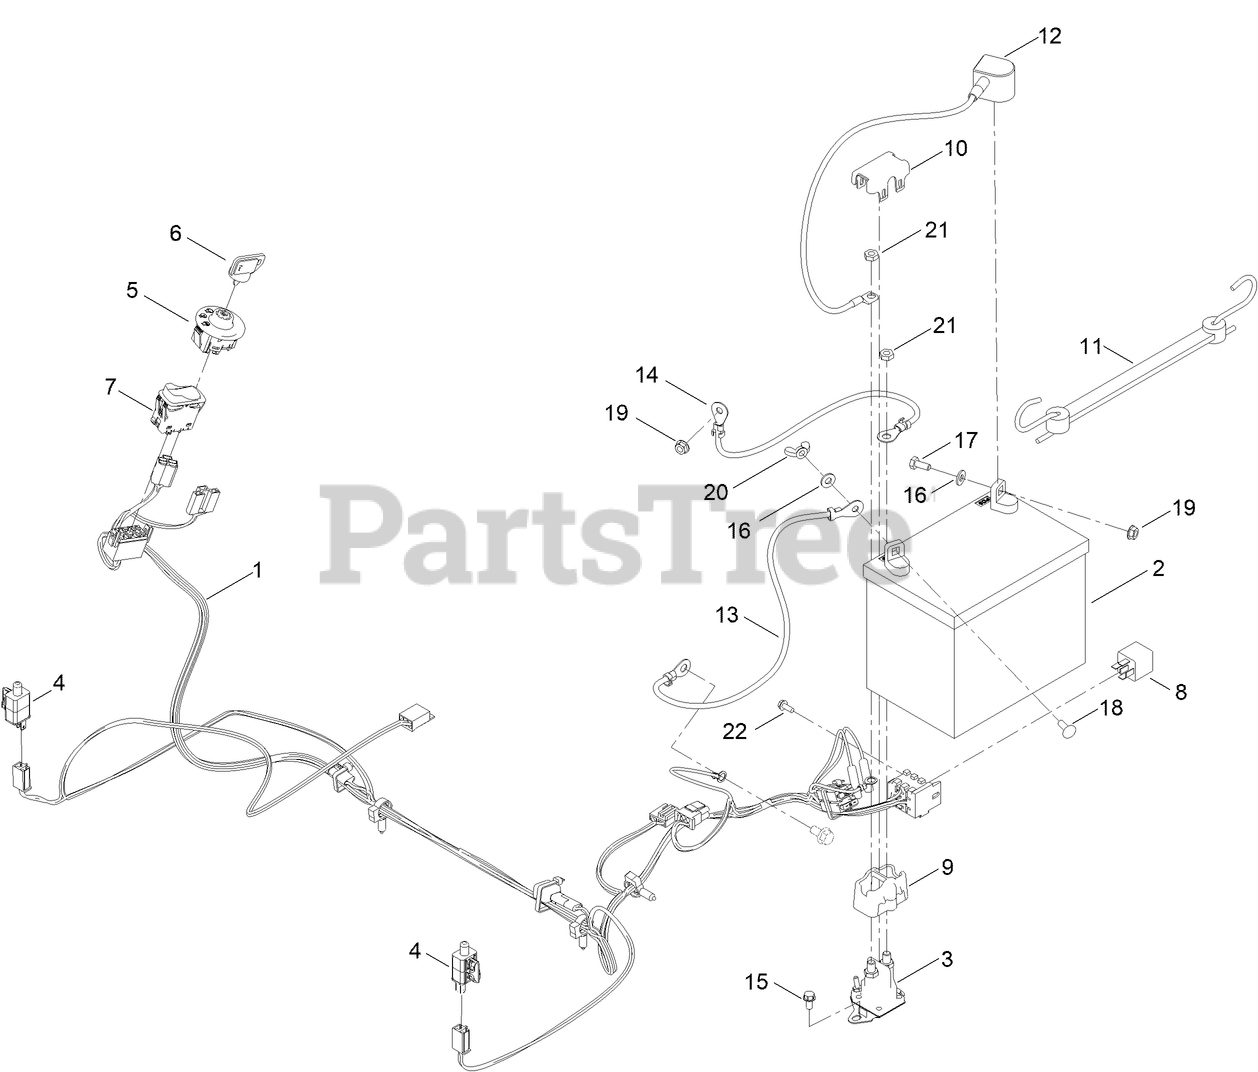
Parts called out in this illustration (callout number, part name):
1	HARNESS-WIRE, MAIN
3	SOLENOID
4	SWITCH
5	SWITCH-IGNITION
6	KEY-IGNITION
7	SWITCH-ROCKER, ON-NONE-ON
9	COVER-SOLENOID
10	CAP-SOLENOID
11	HOLDDOWN-BATTERY
12	CABLE-BATTERY,RED
13	CABLE-BATTERY, BLACK
14	CABLE-BATTERY, POSITIVE
15	SCREW-HWH
16	WASHER-FLAT
17	SCREW-HH
18	BOLT-CARR
19	NUT-HF
20	NUT-WING
21	NUT-JAM
22	SCREW-TAPTITE
